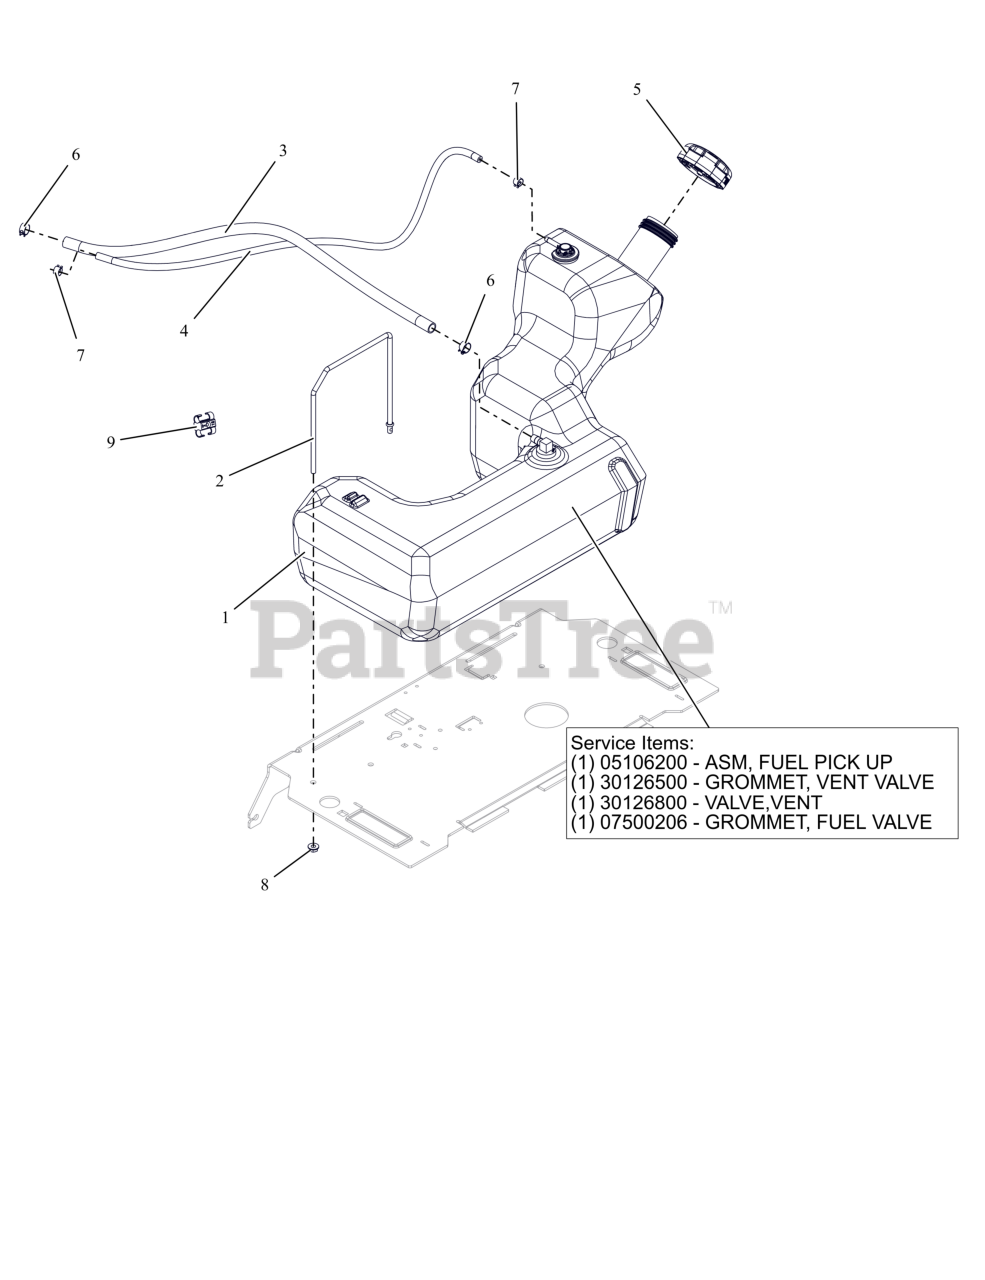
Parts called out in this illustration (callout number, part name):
1	ASM, FUEL TANK - IKON 23
1	ASM, IKON FUEL PICK-UP
1	GROMMET, VENT VALVE
1	VALVE, VENT
1	BSHG-FLG .375X1.062X.625 NITR
2	STRAP, TANK HOLD DOWN
3	1 INCH OF HOSE, .25 LOW-PERM BULK GAS
4	HOSE, .188 30R7 BULK
5	CAP-FUEL- 2.25 RATCHET INLET V
6	CLAMP, FUEL LINE
7	CLAMP-HOSE, SPRING .188
8	NUT-LK-CTR-FLG .25-20 ZC120
9	CLIP, T, .38-.50
